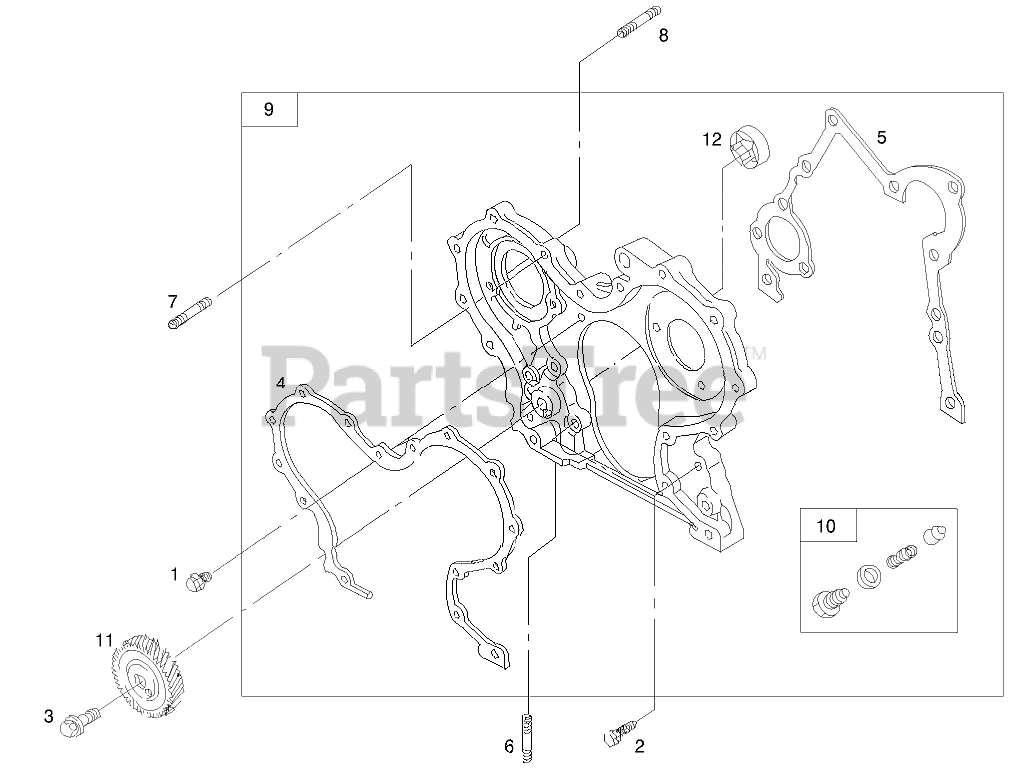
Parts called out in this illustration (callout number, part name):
1	SCREW-HEX
2	SCREW-HEX
3	SCREW-HEX
4	GASKET-COVER, GEAR
4	NIPPLE ASM
5	GASKET-COVER, GEAR
5	VALVE ASM
6	STUD-METRIC
7	STUD-METRIC
8	STUD-METRIC
9	HOUSING-GEAR
9	GASKET-SET
10	VALVE-RELIEF, OIL
11	GEAR-DRIVE
14	VALVE OVERHAUL KIT
15	SHAFT-GEAR
